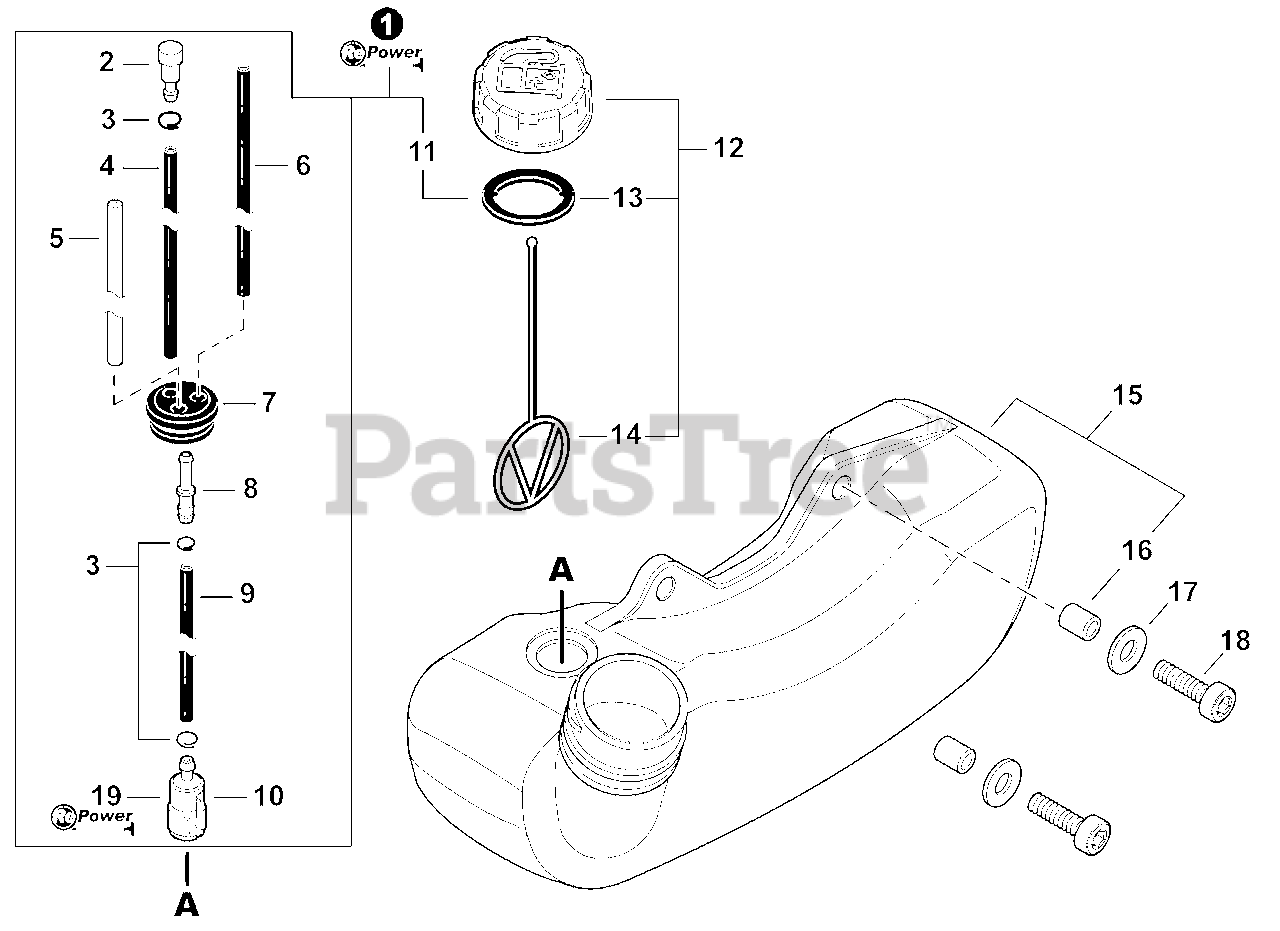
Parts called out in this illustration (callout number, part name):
1	FUEL SYSTEM KIT - REPOWER
2	VENT ASSY
3	CLIP Ø6
4	PIPE, FUEL 3×5×80 BLACK
5	PIPE, FUEL 3×6×85 CLEAR
6	PIPE, FUEL 3×5×78 BLACK
7	GROMMET, FUEL Ø5
8	CONNECTOR, PIPE Ø5ר3.5
9	PIPE, FUEL 3×5×130 BLACK
10	FILTER, FUEL
11	GASKET, FUEL CAP
12	CAP ASSY, FUEL
13	GASKET, FUEL CAP
14	CONNECTOR, CAP L= 100mm
15	TANK ASSY, FUEL
16	SPACER 6.2×7.8×6
17	WASHER 5.5×12×0.8
18	BOLT, TORX 5×16
19	TUNE-UP KIT - REPOWER
